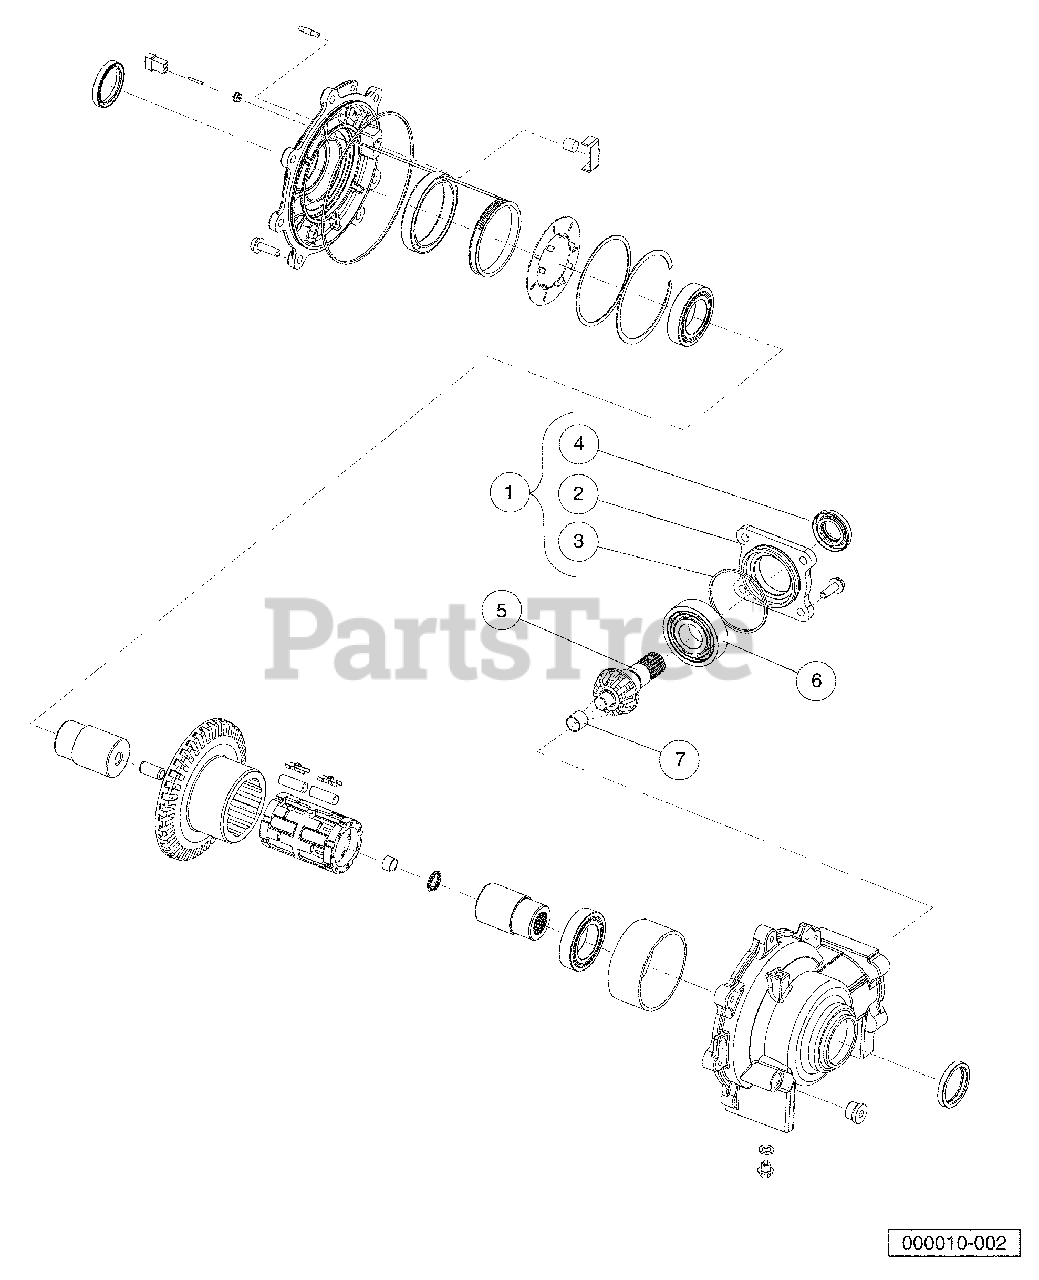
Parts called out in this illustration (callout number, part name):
1	Kit, Assy, Input Cover Plate
2	Cover, Input, Machined
3	O-Ring
4	Oil Seal, Triple-Lipped
5	Shaft, Pinion, Machined
6	Bearing, Ball
7	Bushing, Plain 16 Id X 15 Wide
